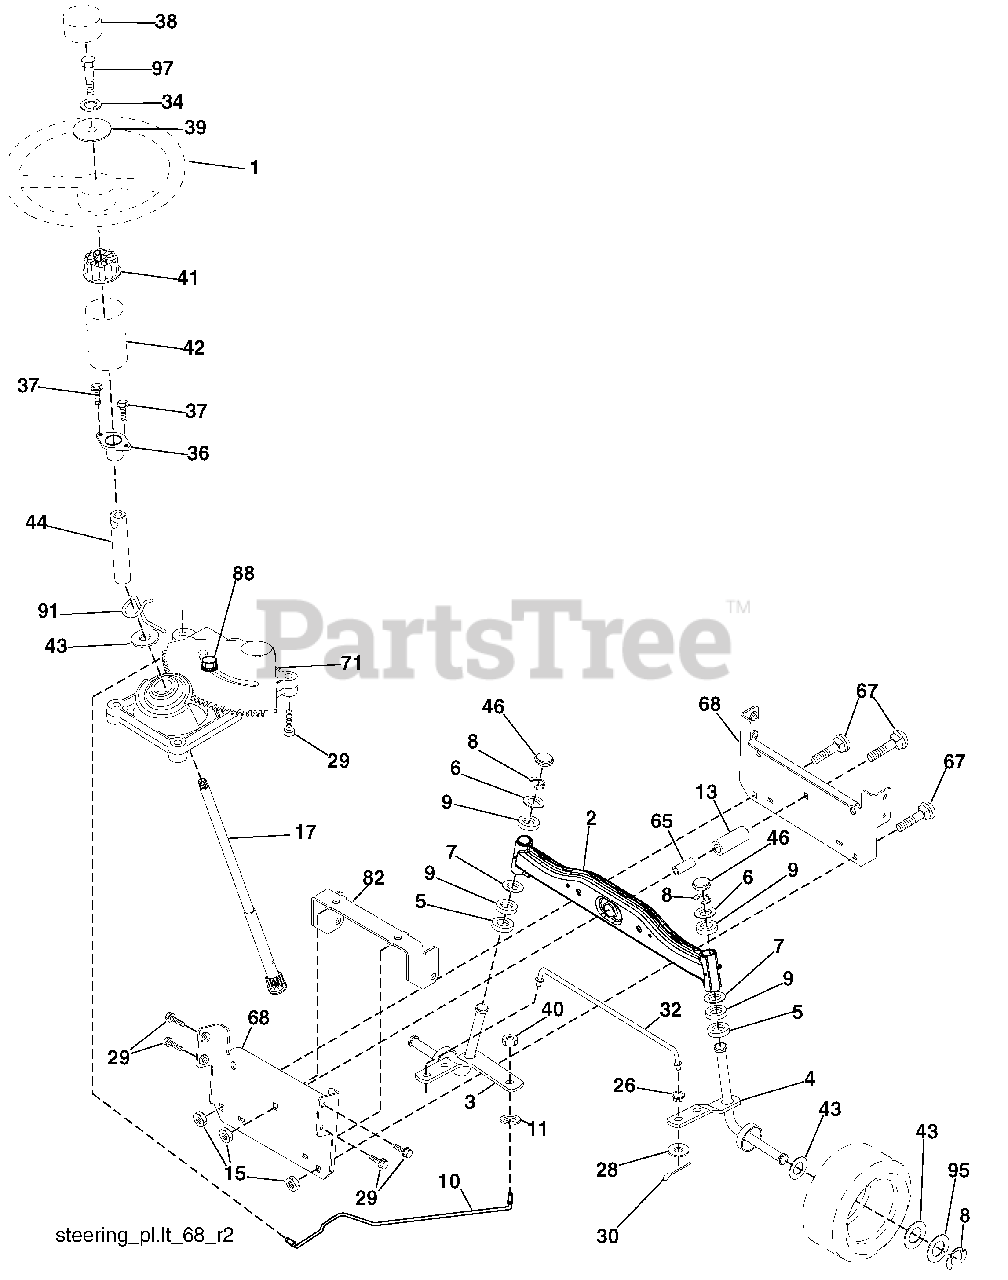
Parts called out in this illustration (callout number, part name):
1	Wheel Steering
2	Axle Asm
3	Spindle Asm LH
4	Spindle Asm RH
5	Bearing Race Thrust Harden
6	Washer 25/32 x 1-5/8 x 16 Ga.
7	Washer 27/32 x 1-1/4 x 16 Ga.
8	Ring Klip #t5304-75
9	Bearing Col Strg Blk
10	Link Drag
11	Washer Lock Hvy Hlcl Spr 3/8
13	Spacer earing Axle Front
15	Hexflange Lock
17	Shaft Asm Strg
26	Bushing Link Drag Blk LR
28	Washer 13/32 x 7/8 x 16 Ga.
29	Screw 3/8-16 x 3/4
30	Pin Cotter 1/8 x 3/4 Cad
32	Rod Tie Wire Form 19 75 Mech
34	Washer Lock Hvy Hlcl Spr 5/16
36	Bushing Strg 5/8 Id Dash
37	Screw
38	Cap Wheel Steer Ayp
39	Washer 11/32 ID x 2-3/8 OD x 12 Ga.
40	Nut Crownlock 3/8-24
41	Adaptor Wheel Strg
42	Boot Dash Mtl Steering Blk
43	Washer 25/32 x 1 1/4 x 16 Ga.
44	Extension Steering
46	Cap Spindle Fr Top Blk
65	Spacer Brace Axle
67	Bolt RDHD SQNK 3/8-16 x 2-1/4
68	Brace Axle
71	Steering Asm.
82	Bracket Susp Chassis Front
88	Bolt Shoulder 7/16-20
91	Clip Steering
95	Washer Harden .793 x 1.637 x 060
97	Bolt 5/16-18 unc x 4"L Hlcl Spr. 5/16
